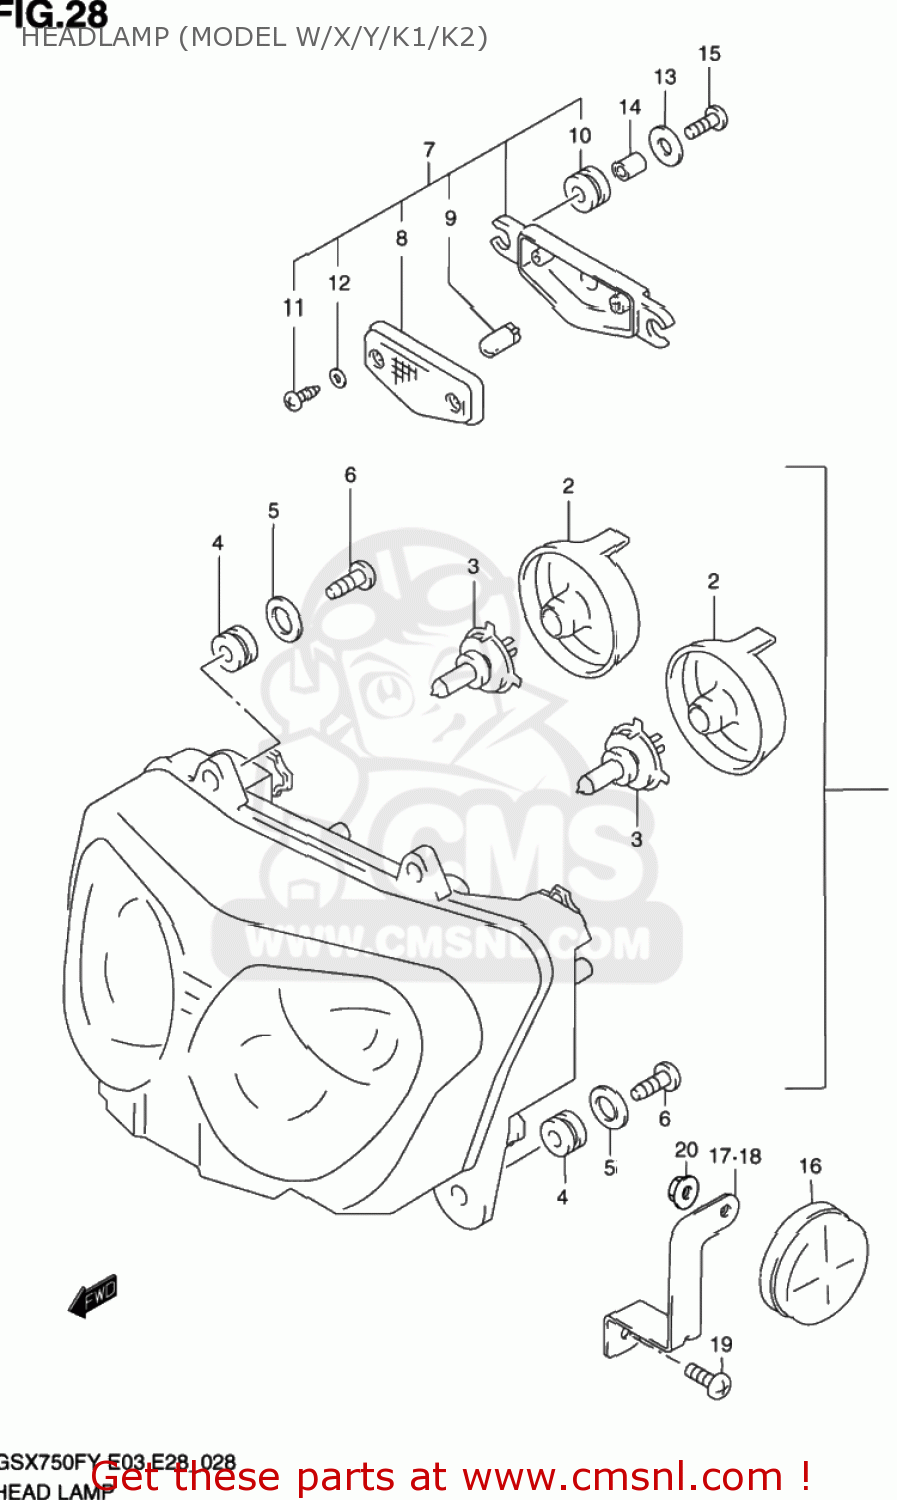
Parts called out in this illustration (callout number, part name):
1	HEADLAMP ASSY
2	COVER,SOCKET
3	BULB(12V60/55W,H4)
4	CUSHION,HEADLAMP
5	WASHER(5.5X18X1)
6	SCREW
7	LAMP ASSY,FR POSITION
8	LENS
9	BULB(12V5W)
10	CUSHION
11	SCREW
12	WASHER
13	WASHER(5.5X18X1)
14	SPACER(5.5X8X10.5)
15	SCREW 5X20
16	REFLECTOR,REFLEX FR
17	BRACKET,FR SIDE
18	BRACKET,FR SIDE RR,L
19	SCREW
20	NUT
